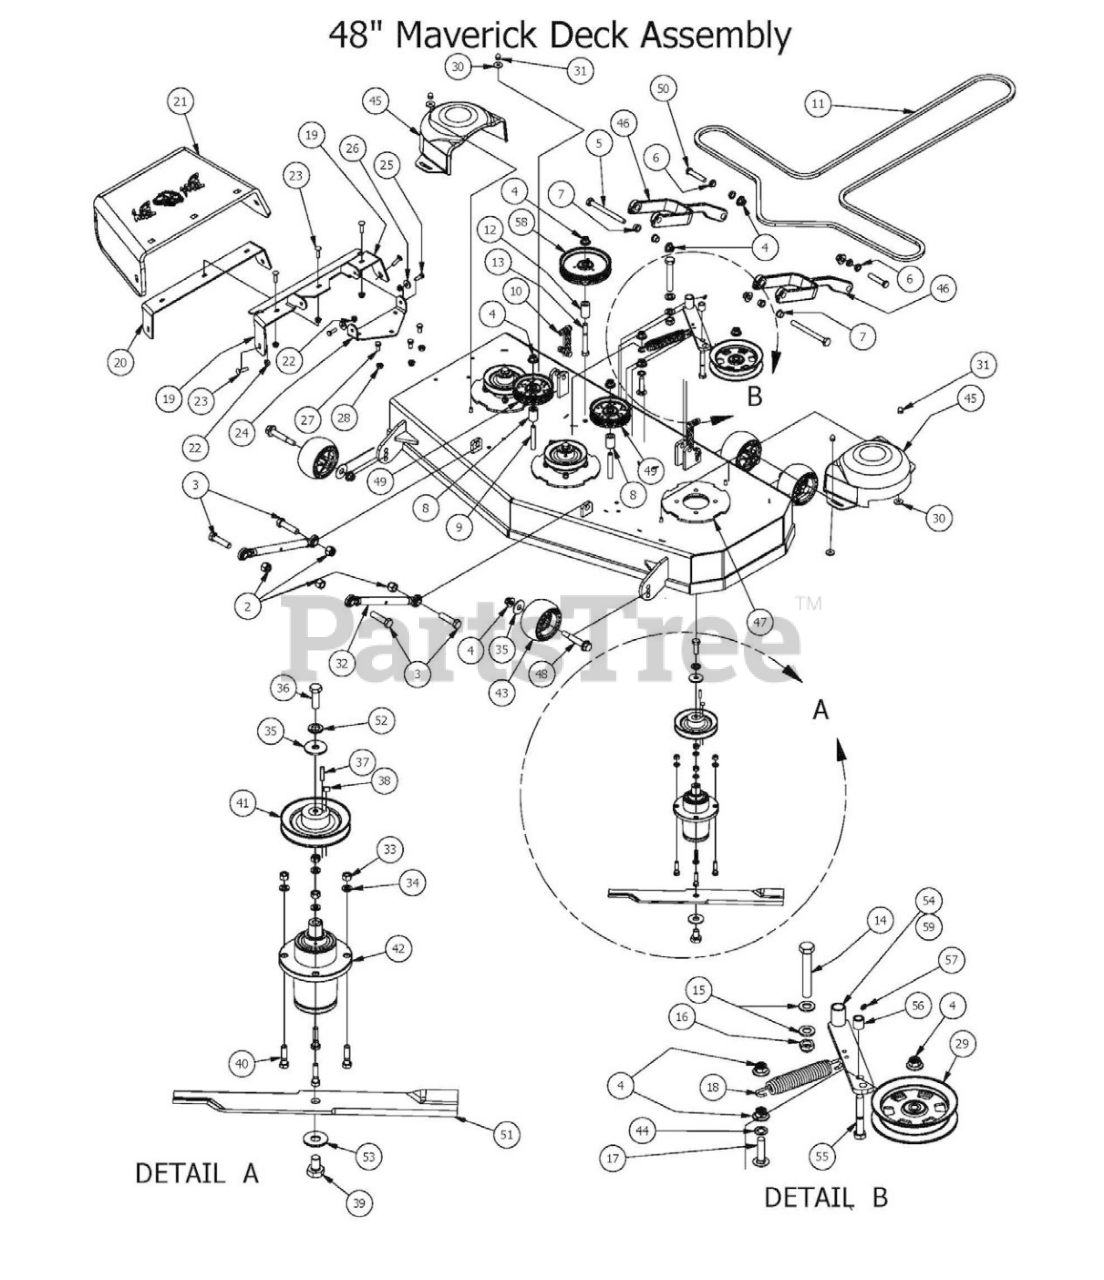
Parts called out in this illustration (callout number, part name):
1	Maverick 48" Deck
2	5/8 Std NC Nylock Nut
3	5/8" x 2 1/2" Grade 5 Hex Bolt (Coarse)
4	1/2-13 Nylon Flange Nut
5	1/2" x 5 1/2" Bolt
6	Flange Bushing For Lower Deck Arm
7	Flange Bushing For Upper Deck Arm
8	Idler Pulley Standoff
9	1/2 x 3 1/2 Flange Bolt Grade 8
10	6 Link Chain assembly
11	48 Deck Belt
12	1 3/4" Pulley Spacer
13	1/2" x 4" Bolt (Grade 8)
14	5/8" x 4" Hex Bolt
15	.630 ID Plastic Washer
16	5/8-11 Nylon Insert Jam Half Nut
17	1/2 x 2" Carriage Bolt
18	2015 Deck Idler Spring
19	Discharge Upper Chute Bracket
20	Discharge Lower Chute Bracket
21	Rubber Discharge Chute
22	5/16" Nylon Flange Nut
23	5/16" x 1 1/4" Carriage Bolt
24	Discharge Chute Hanger (Deck Mounted)
25	5/16" x 1" Bolt
26	.360 ID Plastic Washer
27	3/8" x 3/4" Hex Bolt
28	3/8" Flange Nut
29	5" Idler Pully
30	.360 ID Plastic Washer-Black
31	Acorn nut-pulley Cover
32	Turnbuckle (Top Link)
33	3/8" Hex Nut
34	3/8" Lock Washer
35	1/2" Belleville Washer
36	1/2"-20 x 1 1/2 - Grade 5 Fine Thread Bolt
37	1/4" x 1" Key
38	5/16 Set Screw
39	5/8" x 1 1/2" Grade 8 Hex Bolt (Fine)
40	3/8" x 1 1/2" Hex Bolt
41	5" Spindle Deck Pulley
42	Spindle Assembly
43	Anti-Scalp Roller
44	.517 Square Hole Round Washer
45	Pulley Cover
46	Deck Arm Assembly
47	Deck Spindle Support Plate
48	Deck Wheel Bolt
49	4-3/4 Idler Pulley
50	1/2" x 3" Hex Bolt
51	Fusion Blade
52	1/2" Lock Washer Zinc
53	5/8" Flat Washer
54	Deck Idler
55	1/2 x 2-3/4 Hex Bolt
56	Spacer 3/4 OD x 1/2 ID x 314 Length
57	1/4" Drive in Grease Fitting
58	5-3/4 Idler Pulley-Capitol Stampings
59	Idler Arm Assembly (Parts 4,29,54,55,56,57)
